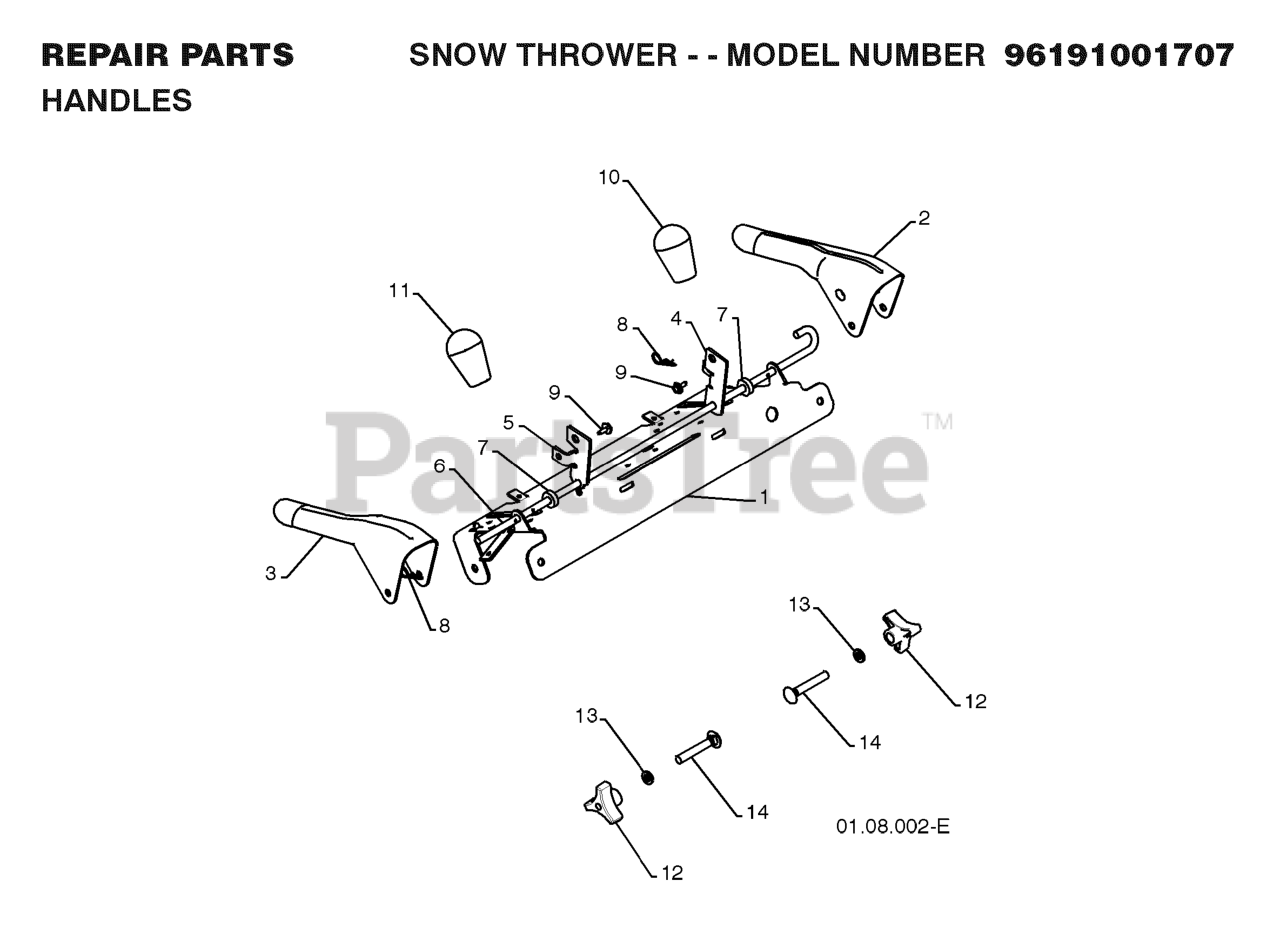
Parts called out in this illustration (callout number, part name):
1	PANEL.CONTROL.PNT.BLACK
2	LEVER.CONTROL.LH.PNT
3	LEVER.CONTROL.RH.PNT
4	ARM.TRACTION.ROD.YZ
5	ARM.IMPELLER.ROD.
6	BAIL.CONTROL.INTERLOCK
7	SPACER.CONTROL.LEVER
8	SPRING RETAINER
10	KNOB LEVER, BLACK
11	RED KNOB SHIFTER
12	KNOB.HANDLE.3/8.TRI-POINT.BLAC
13	WASHER
14	BOLT 3/8-16 X 2-1/4
